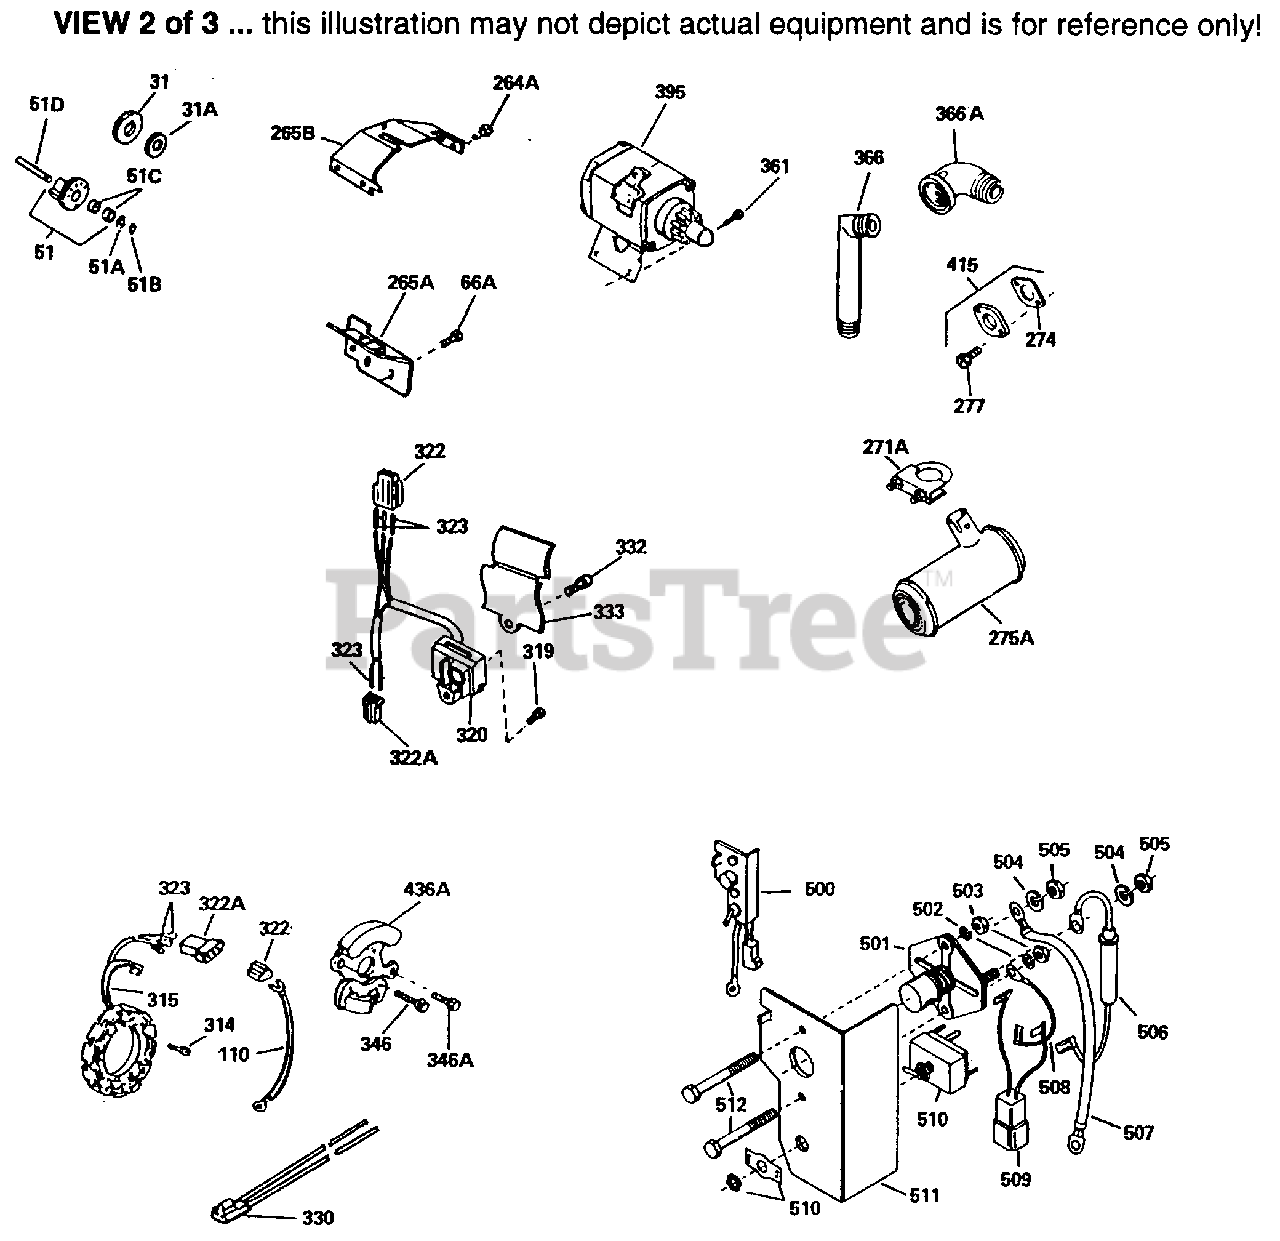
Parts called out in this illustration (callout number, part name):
3	Screw, 5/16-18 x 1/2"
16B	Governor Spring Plate
46	Connecting Rod Bolt
50	Camshaft (MCR)
65	Screw, 10-24 x 1/2"
72A	Oil Drain Plug
80	Governor Shaft
84	Retaining Ring
92	Lock Washer
149A	Valve Spring Cap (1/32" OS Stem)
149C	Valve Pin
183	Choke Bracket
242A	Air Cleaner Bracket
260	Blower Housing
265	Cylinder Head Cover
298A	Lock Nut, 1/4-20
298B	Screw, 5/16-18 x 5/8"
298C	Washer
305	Oil Fill Tube
314	Screw, 10-32 x 1-1/8"
315	Alternator Coil (20 Amp) Incl. 322 - 323
319	Screw, 5/16-24 x 3/8"
319	Screw, 1/4-20 x 1/2"
320	Regulator (20 Amp)
322	Connector Body
322A	Connector Body
323	Terminal
355	Starter Handle
361	Screw, 5/16-18 x 11/16"
366A	Muffler Nipple
395	Electric Starter Motor (12 Volt)
